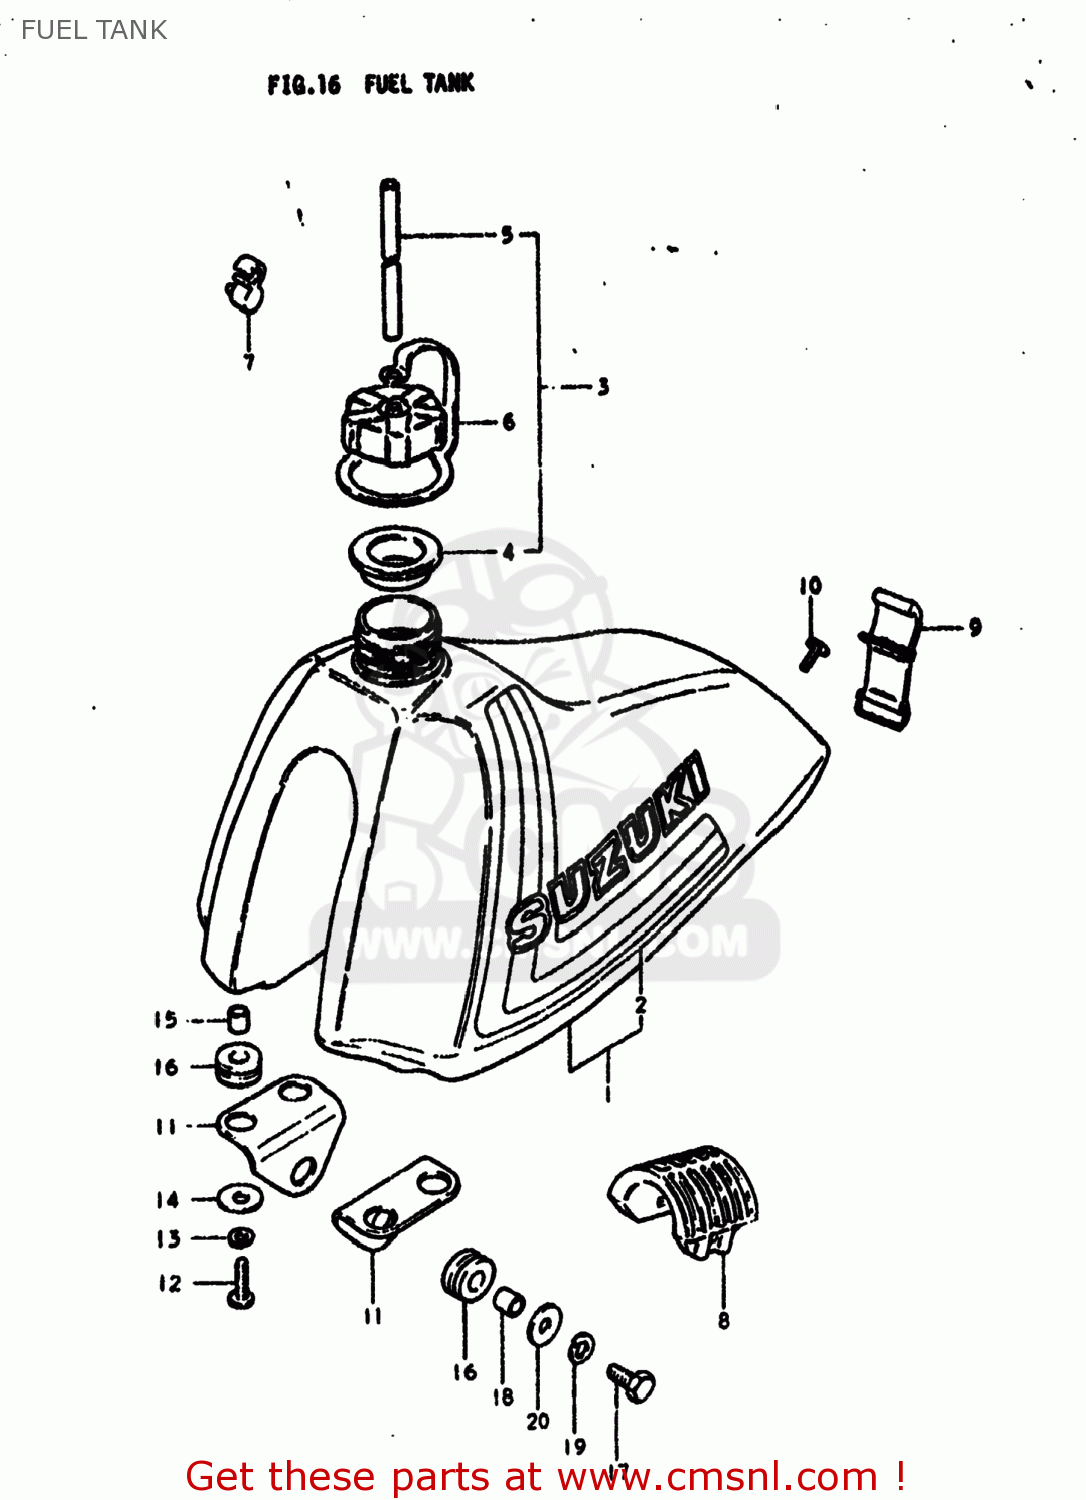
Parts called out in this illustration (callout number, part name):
1	TANK ASSEMBLY,FUEL
3	CAP SET,FUEL TANK
4	GASKET,FUEL TANK CAP (NAS)
5	HOSE
6	BAND,FUEL TANK CAP
7	CLAMP,FUEL TANK BREATHER HOSE
8	CUSHION,FUEL TANK
9	BAND
10	SCREW(6X18)
11	BRACKET,FUEL TANK
12	SCREW
13	LOCK WASHER
14	WASHER (6.5X24X1.6)
15	SPACER(6.8X12X11)
16	CUSHION
17	BOLT
18	SPACER (8.8X12X11)
19	LOCK WASHER
20	WASHER (8.2X24X1.6)
